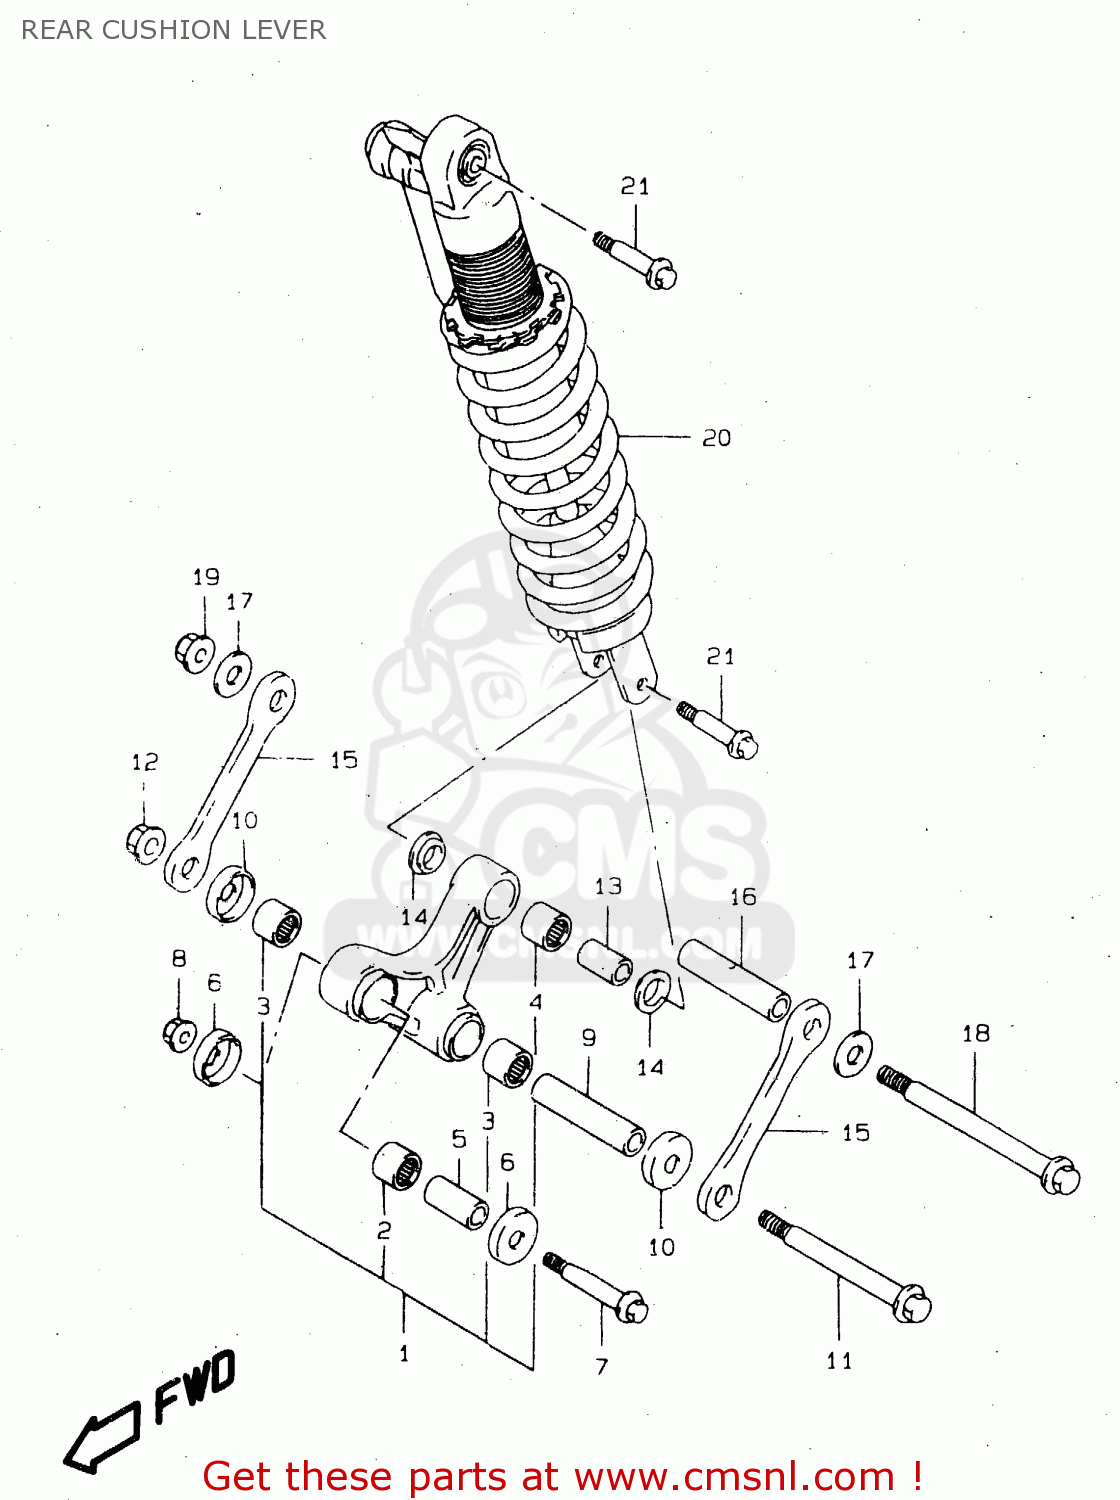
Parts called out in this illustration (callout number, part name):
1	LEVER SET,RR CUSHION
2	BEARING(20X27X30)
3	BEARING(21X27X20)
4	BEARING(17X24X20)
5	SPACER,RR CUSHION LEVER FR
6	SEAL,RR CUSHION LEVER FR DUST
7	BOLT,RR CUSHION LEVER FR
8	NUT 12MM
9	SPACER,RR CUSHION LEVER CTR
10	SEAL,RR CUSHION LEVER CTR
11	BOLT,RR CUSHION LEVER CTR
12	NUT
13	SPACER,RR CUSHION LEVER
14	SEAL,RR CUSHION LEVER RR DUST
15	ROD,RR CUSHION LEVER
16	SPACER,RR CUSHION LEVER CTR
17	WASHER
18	SHAFT,RR CUSHION LEVER FR
19	NUT
20	ABSORBER ASSEMBLY,REAR SHOCK
21	BOLT,RR CUSHION ROD UPR
